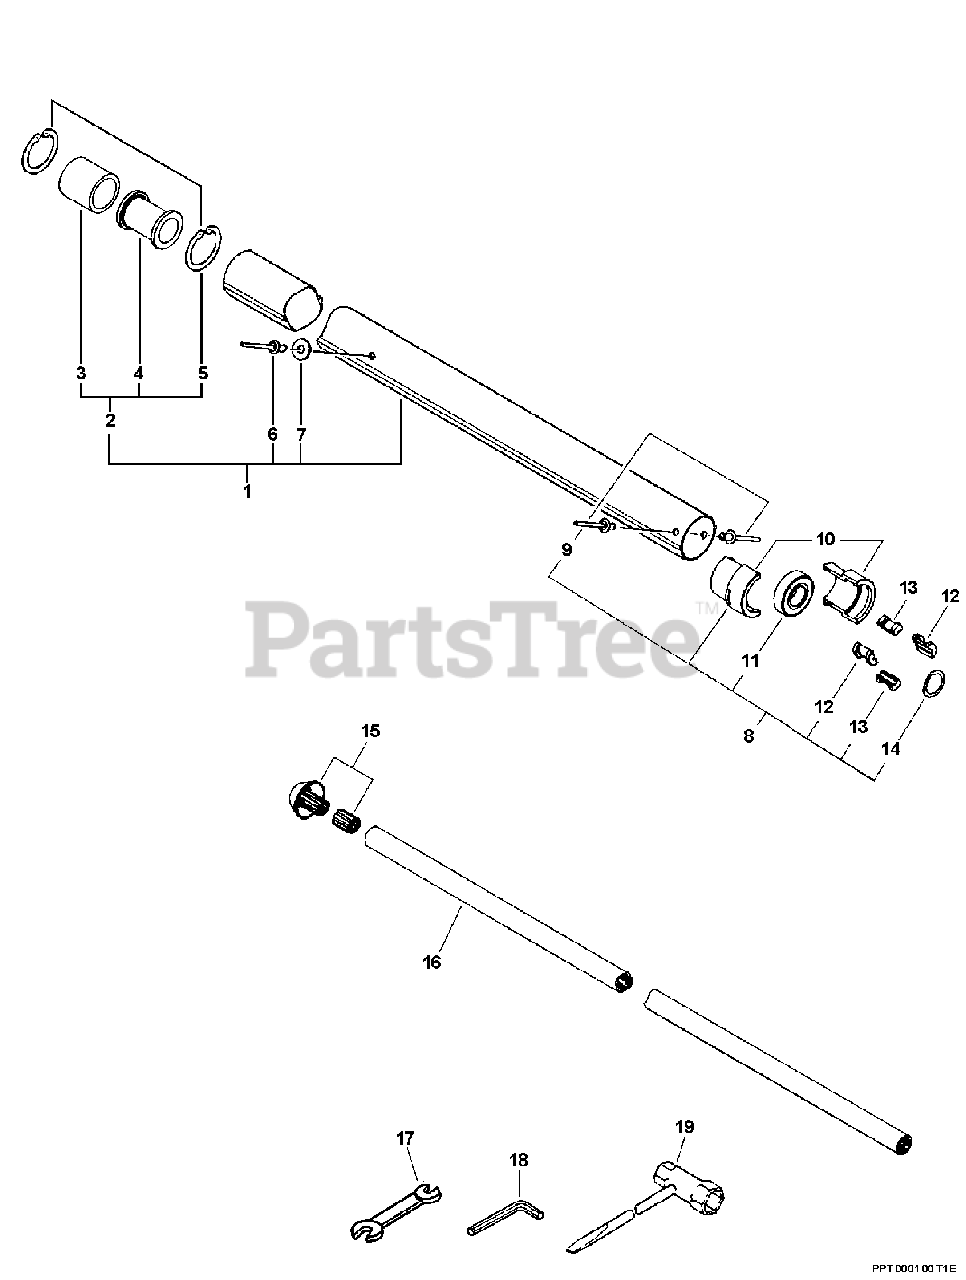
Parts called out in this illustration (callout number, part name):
1	PIPE, MAIN - BLACK
2	DRIVESHAFT GUIDE ASSY
3	PAD, FOAM
4	GUIDE, DRIVESHAFT
5	RING, SNAP
7	WASHER, FLAT 5
8	HOLDER ASSY, BEARING
10	HOLDER, BEARING
11	BEARING, BALL 6002 DDU
12	GUIDE, SHAFT - LARGE
13	GUIDE, SHAFT - SMALL
14	WASHER, WAVE
15	ADAPTER, UPPER DRIVE SHAFT
16	DRIVESHAFT
17	SPANNER 8×10
18	WRENCH, ALLEN 3 MM
19	TOOL, BOX SPANNER
